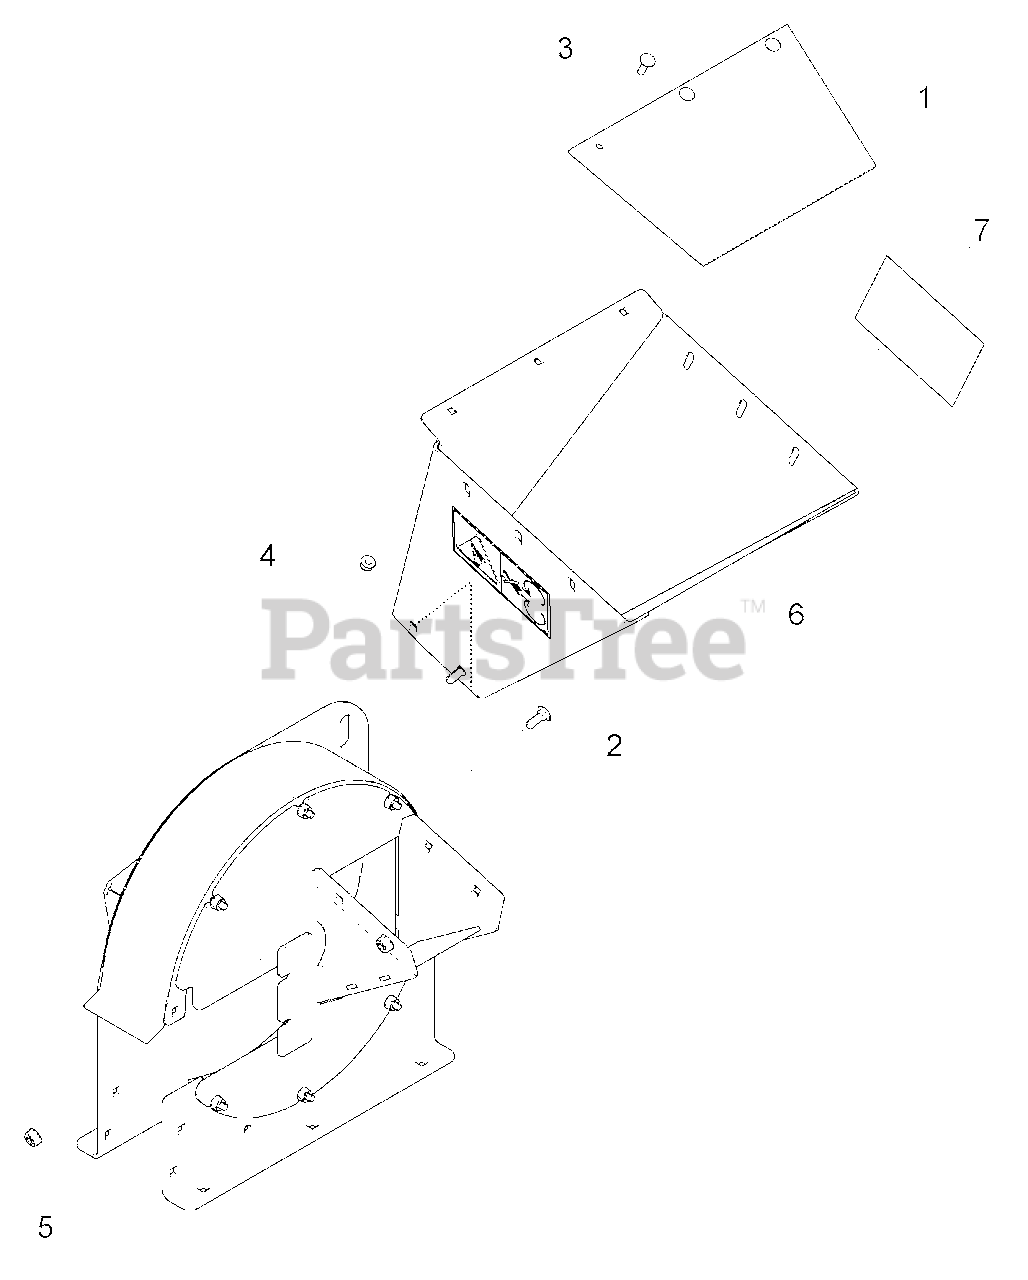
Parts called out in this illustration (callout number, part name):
1	FLAP, CHIPPER CHUTE
2	BOLT, 3/8 X 1" CRG GR5 NC ZP
3	BOLT, 5/16 X 1" GR5 CRG ZP
4	NUT, 5/16-18 NYLOCK FLANGE
5	NUT, 3/8-16 NYLOCK FLANGE
6	ASSEMBLY, HOPPER
7	DECAL, BLADE DANGER ISO
